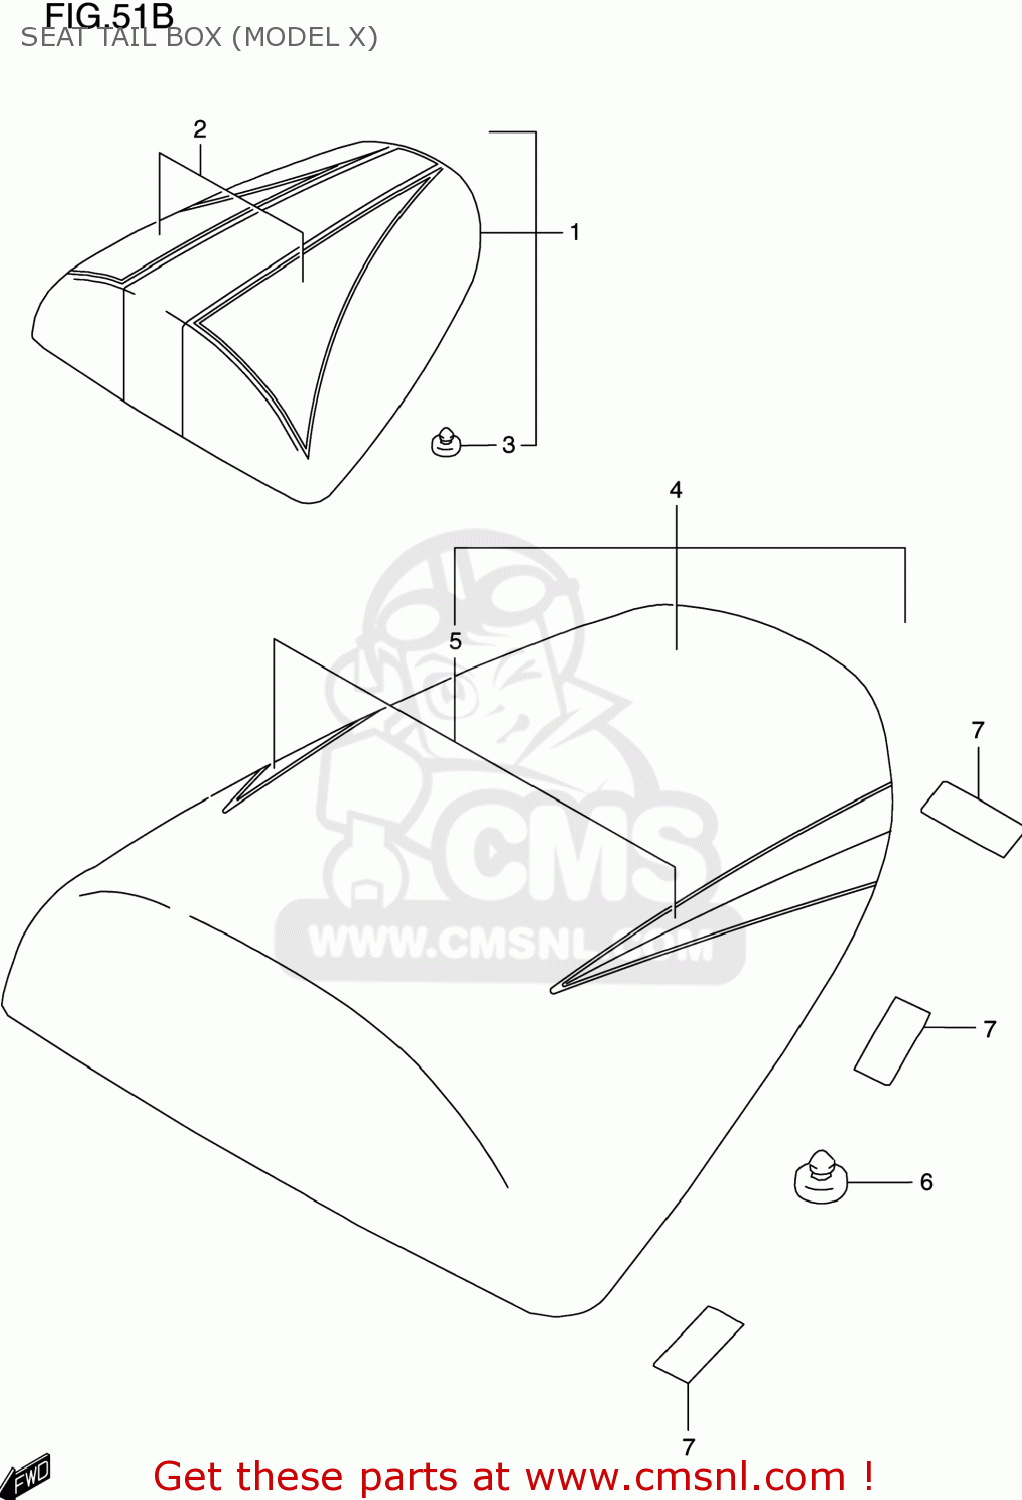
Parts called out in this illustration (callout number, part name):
1	BOX ASSY,SEAT TAIL(WHITE)
2	TAPE SET,BOX SEAT TAIL
3	CUSHION(11.5X22X20)
4	BOX ASSY,SEAT TAIL(BLACK)
5	TAPE SET,BOX SEAT TAIL
6	CUSHION(11.5X22X20)
7	PROTECTOR SET,SEAT TAIL BOX
